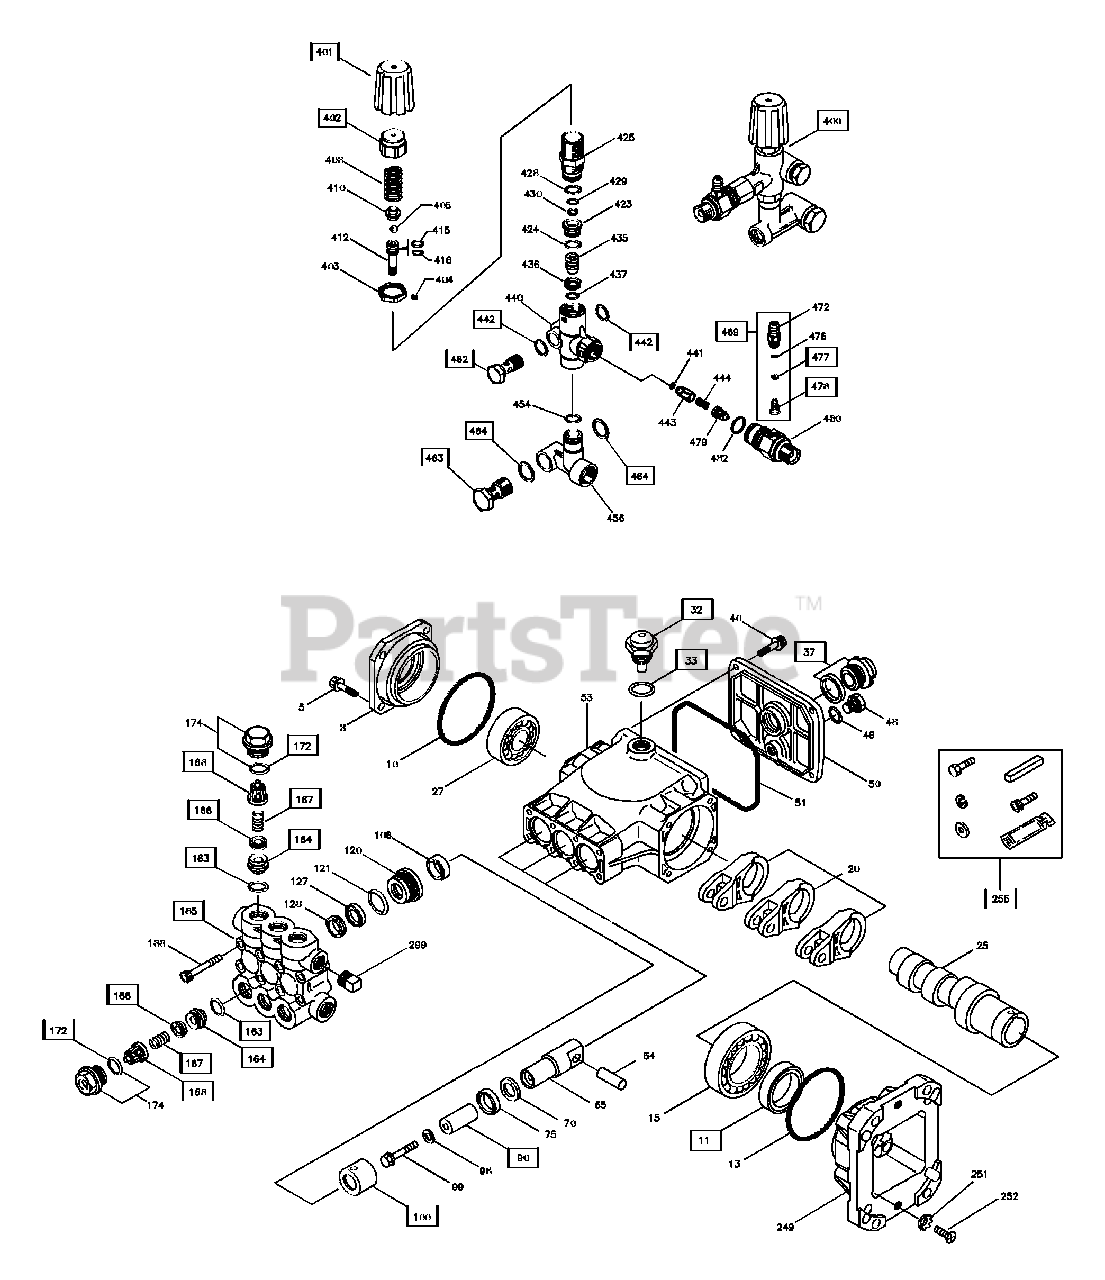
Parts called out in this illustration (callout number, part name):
11	SEAL, Oil, Crankshaft
32	DOMED, Oil Filler
33	O-RING, Filler Cap
37	GAUGE, Oil Sight w/Gasket
100	RETAINER, Seal
163	O-RING, Seat
168	RETAINER, Spring
172	O-RING, Valve Plug
255	KIT, Mounting Bolt
300	KIT, Seal
310	KIT, Valve
400	ASSY, UNLOADER, COMPLETE
401	HANDLE, Adj.
402	CAP, Adjusting
442	WASHER, Seal
462	SCREW, Flow-thru
463	SCREW, Flow-thru
464	WASHER, Seal
468	KIT, O-Ring
469	ASSY, Fixed Barb
